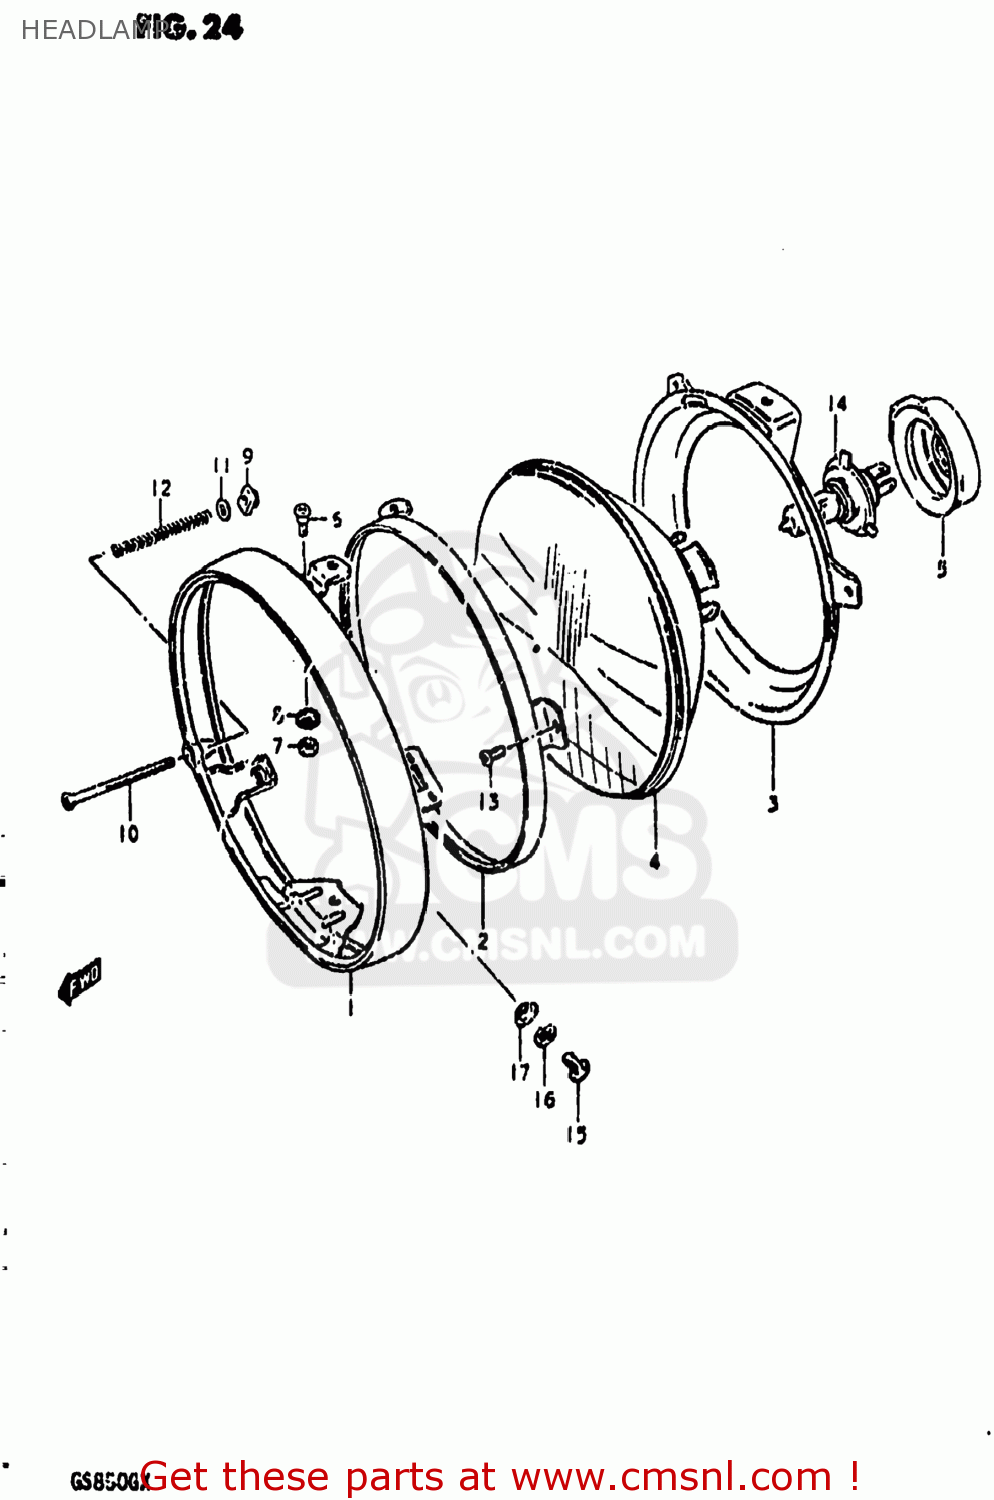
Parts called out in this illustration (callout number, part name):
1	RIM
2	RETAINER
3	RING,HEADLAMP UNIT
4	LAMP UNIT
5	COVER,HEADLAMP SOCKET
6	SCREW
7	NUT,ADJUSTING
8	SPACER
9	NUT
10	SCREW,HEADLAMP ADJUST
11	WASHER
12	SPRING,HEADLAMP ADJUST
13	SCREW
14	BULB(12V60/55W,H4)
15	SCREW
16	WASHER,LOCK
17	WASHER
